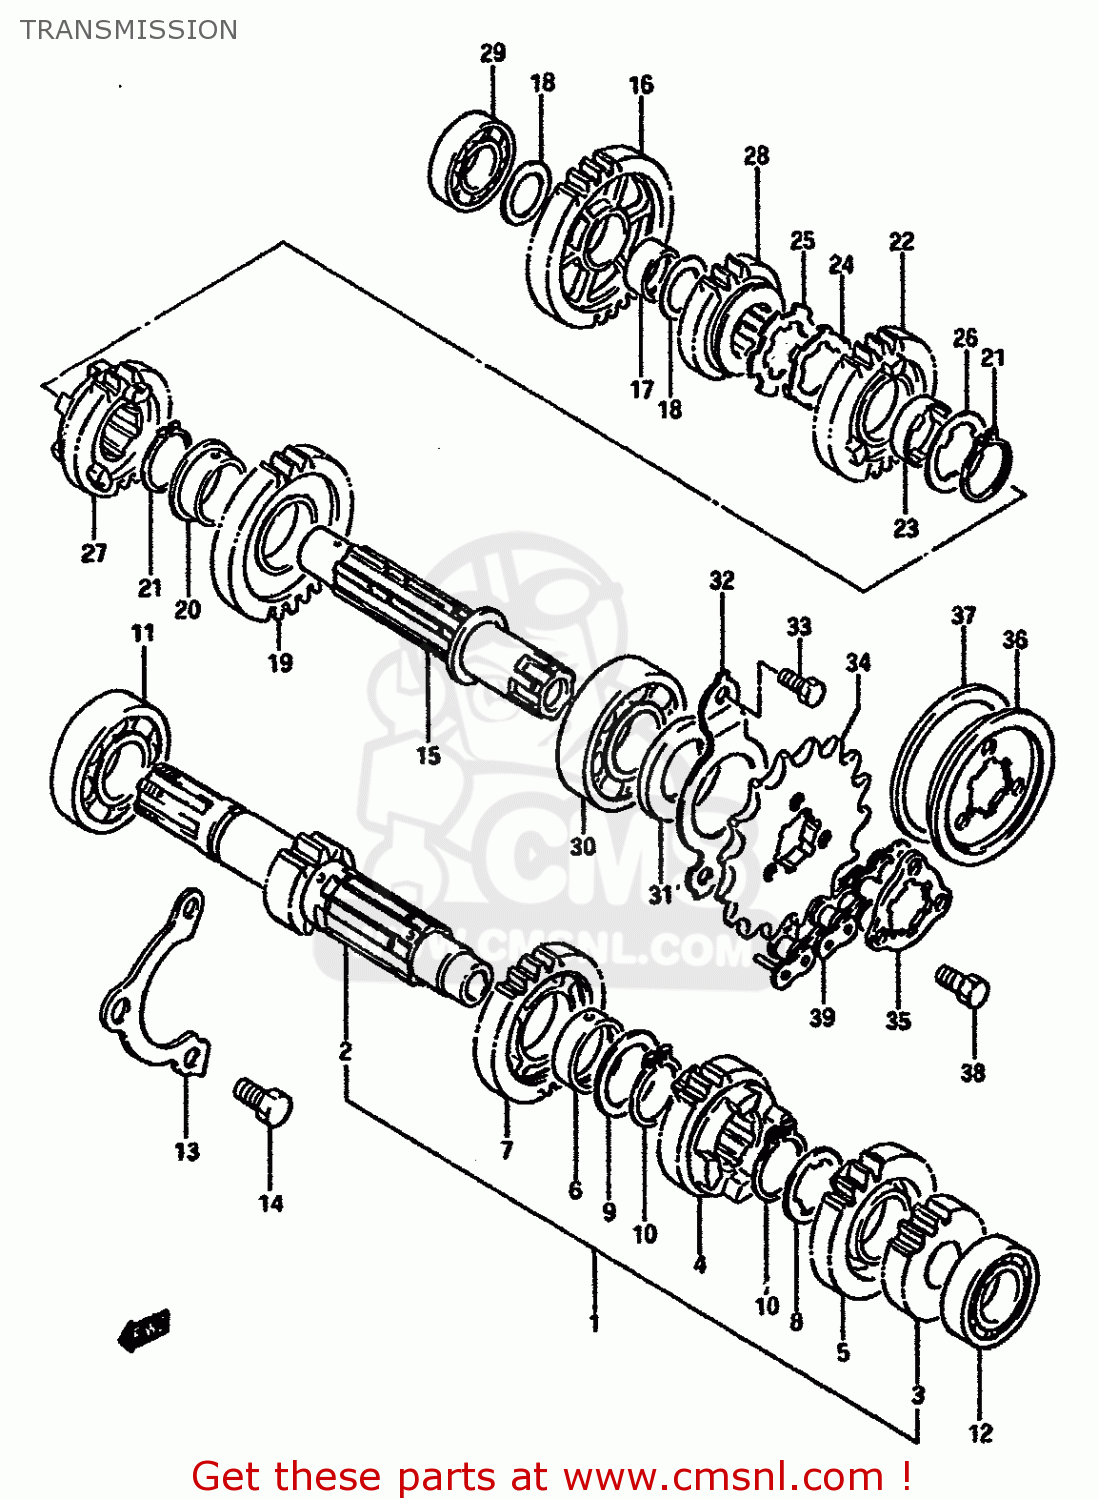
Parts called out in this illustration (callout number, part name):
1	SHAFT ASSEMBLY,COUNTER
2	SHAFT,COUNTER
3	GEAR,SECOND DRIVE
4	GEAR,THIRD/FOURTH DRIVE (NT:
5	GEAR,FOURTH DRIVE
6	BUSHING 25X29X10
7	GEAR,5TH DRIVE
8	WASHER,LOCK
9	WASHER
10	RING,SNAP
11	BEARING
12	BEARING
13	RETAINER,CNTR SHAFT BEARING
14	BOLT, 8X1.25X1
15	SHAFT,DRIVE
16	GEAR,FIRST DRIVEN
17	BUSH(20X24X13)
18	WASHER
19	GEAR,2ND DRIVEN
20	BUSH
21	RING,SNAP
22	GEAR,THIRD DRIVEN
23	BUSHING
24	WASHER
25	WASHER,LOCK
26	WASHER,LOCK
27	GEAR,FOURTH DRIVEN
28	GEAR,FIFTH DRIVEN
29	BEARING(20X42X12)
30	BEARING(25X62X17)
31	SEAL,OIL(25X45X5)
32	RETAINER,DRIVESHAFT O
33	BOLT
34	SPROCKET,ENGINE(NT:16)
35	PLATE,ENGINE SPROCKET
36	PLATE,ENGINE SPROCKET
37	DAMPER,ENGIN SPROCKET
38	BOLT(6X13)
39	CHAIN ASSEMBLY,DRIVE
